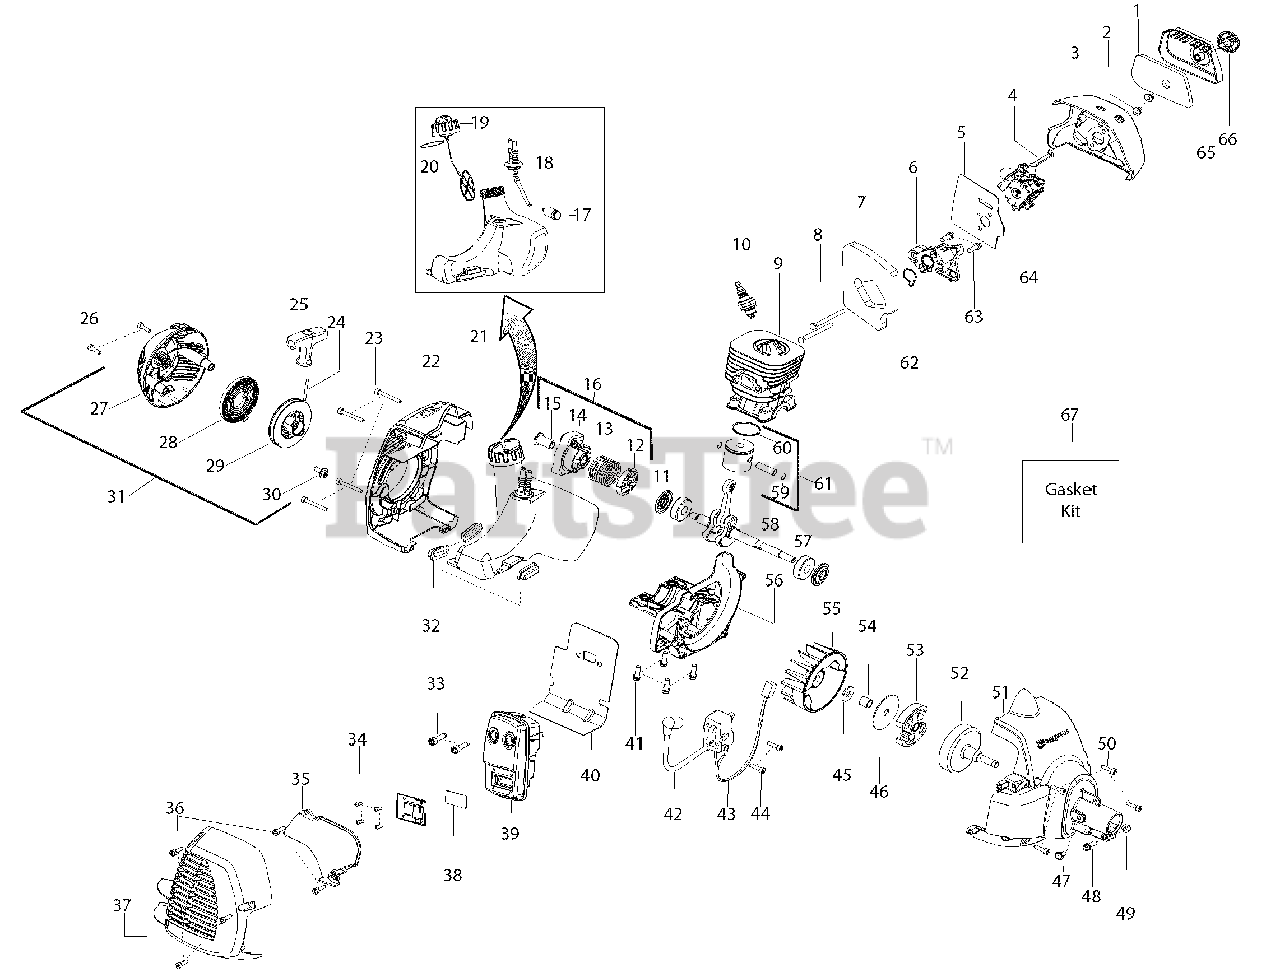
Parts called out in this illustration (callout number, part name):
2	Nut-Carb. Screw
3	Air Box
4	Lever - Choke
5	Kit-Carb. Gasket
6	Adaptor-Carb.
7	Kit-Gasket
9	Cylinder
10	Plug-Spark
11	Kit-Crankshaft seal
12	Washer - Starter
13	Spring - Starter Cup
14	Assy - Starter Cup
15	Coupling - Starter
16	Kit - Starter
17	Assy - Fuel Filter
18	Kit - Fuel Line
19	Assy-Cap w/ret.
20	O-ring - Fuel Cap
21	Assy-Fuel Tank
22	Shroud-Rear
25	Handle - Starter
27	Starter Hsg. w/eyelet
28	Kit-Starter Spring
29	Kit-Starter Pulley
31	Assy-Starter Hsg.
32	Isolator-Tank
33	Bolt-Muffler
35	Shield-Heat
37	Guard-Muffler
38	Kit-Spark Arrestor
39	Assy-Muffler
40	Gasket-Paper Metal
42	Module
43	Assy-Leadwire
46	Washer-Clutch
51	Assy-Fan Housing
52	Assy-Clutch Drum
53	Kit-Clutch Assy.
58	Kit-Crankshaft
59	Retainer-Piston Pin
60	Ring-Piston
61	Kit-Piston
62	Kit-Gasket
64	Kit-Carb.
65	Cover-Air Box
67	Kit-Gasket
